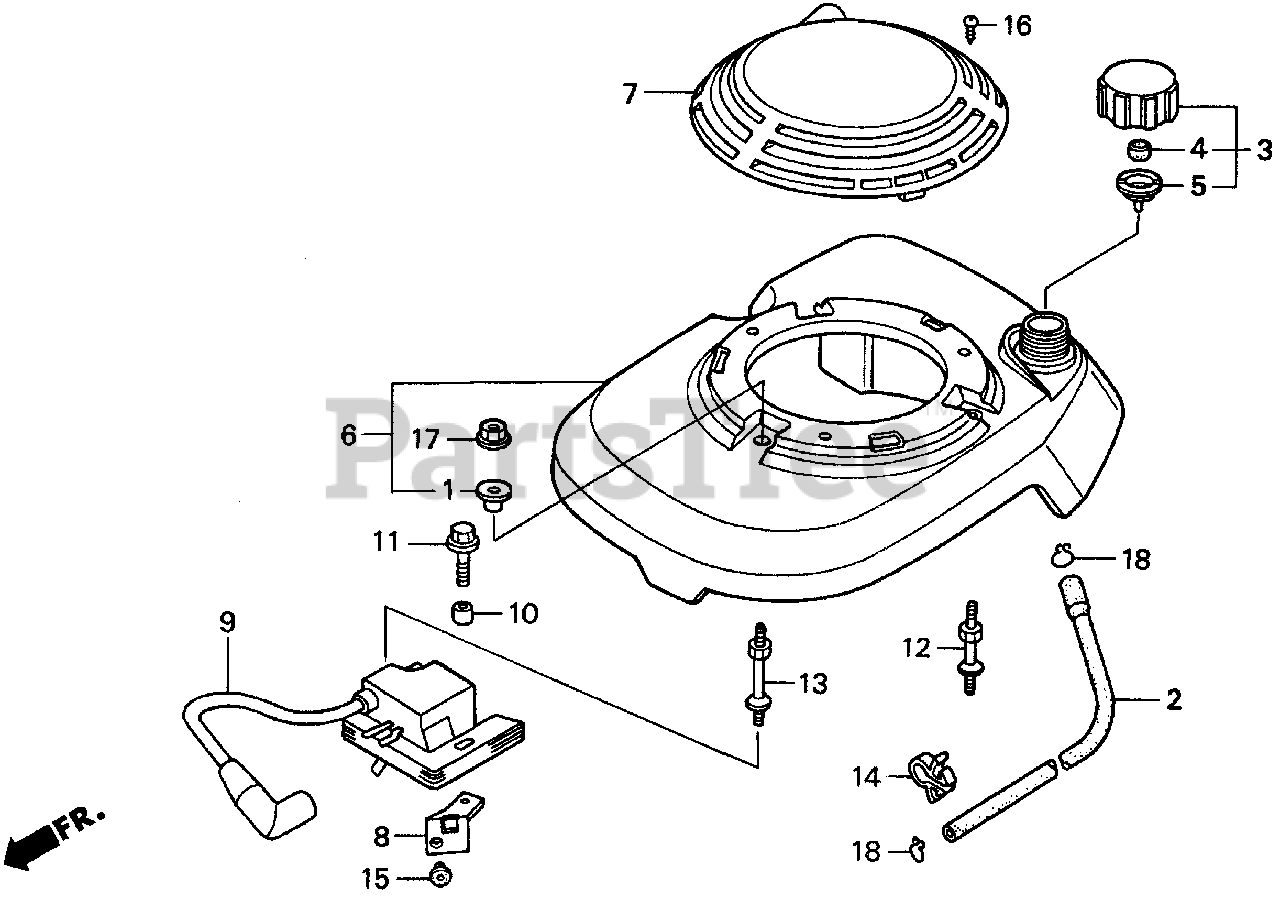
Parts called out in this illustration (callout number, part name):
1	COLLAR, AIR CLEANER (TOYO ROKI)
2	TUBE, FUEL TANK (135MM)
3	CAP ASSY., FUEL TANK
4	SPONGE, FUEL CAP BREATHER
5	GASKET, FUEL CAP
6	COVER, FAN
7	HOOD, FAN COVER *R8* (SMOOTH) (BRIGHT RED)
8	GUIDE, FAN COVER
9	COIL ASSY., IGNITION
10	COLLAR, ROTO-STOP
11	BOLT, FLANGE (6X32)
12	BOLT, STUD (BRAKE)
13	BOLT C, STUD
14	CLIP B, CABLE
15	GROMMET, DEFOGGER CORD (15MM)
16	SCREW, TAPPING (4X20)
17	NUT, FLANGE (6MM)
18	CLIP, TUBE (B10)
